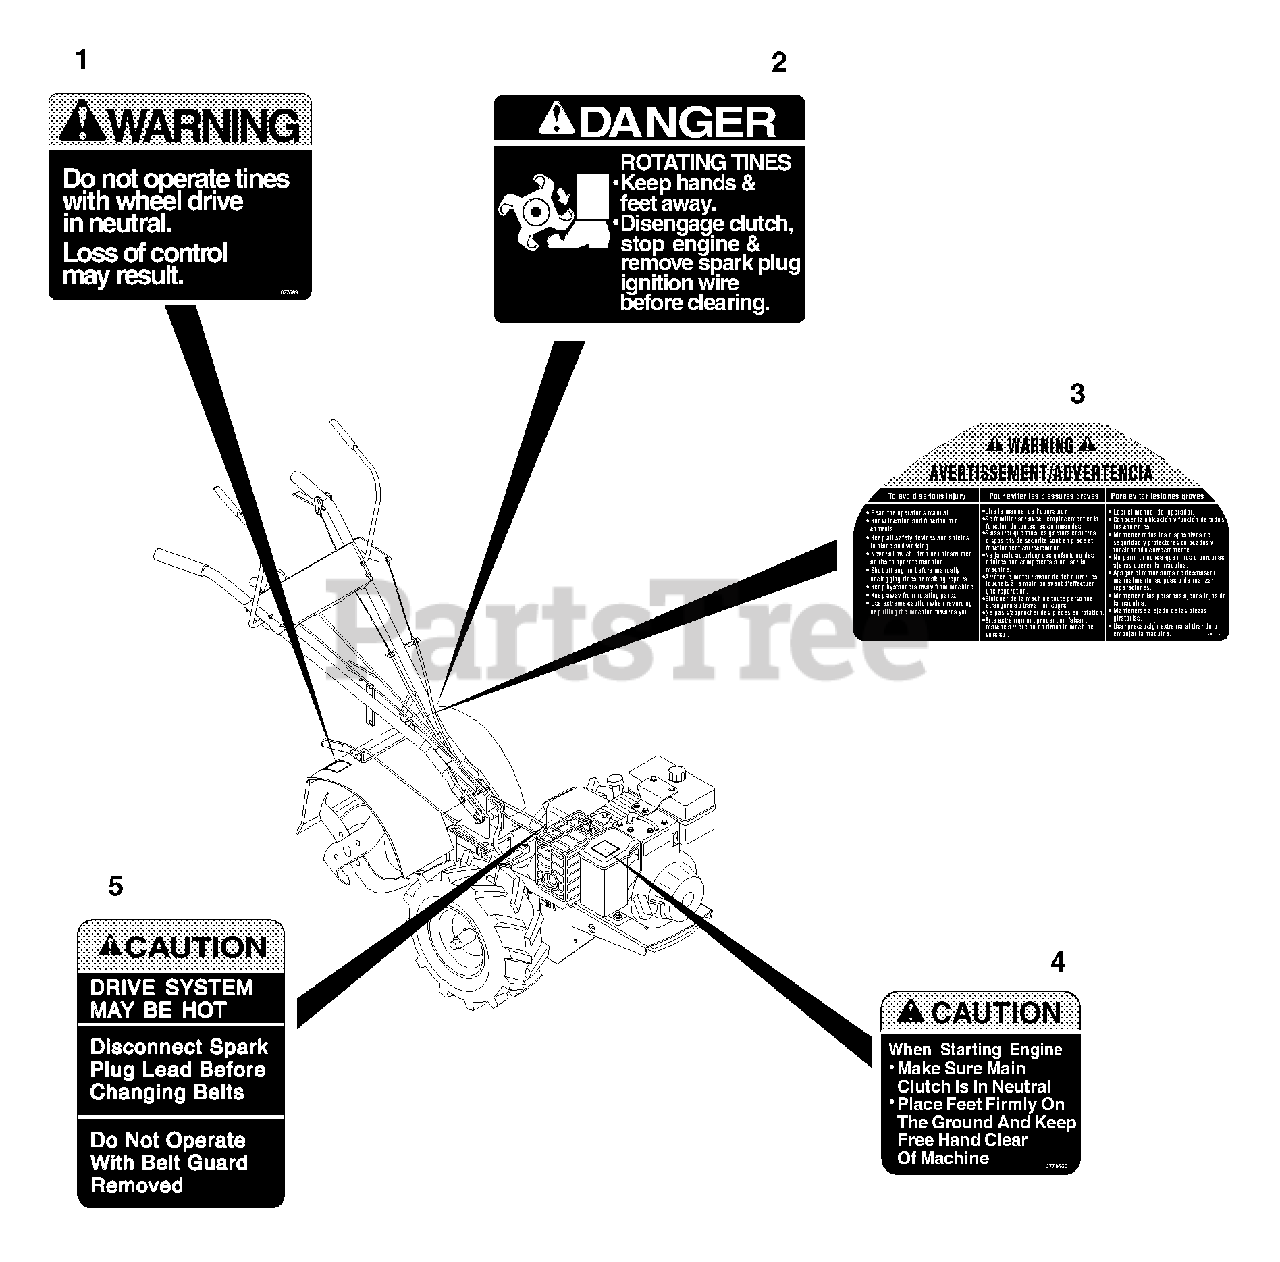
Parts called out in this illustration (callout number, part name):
1	DECAL - WARNING
2	DECAL - DANGER ROTATING TINES
3	DECAL, WARNING
4	CAUTION DECAL
5	CAUTION DECAL
